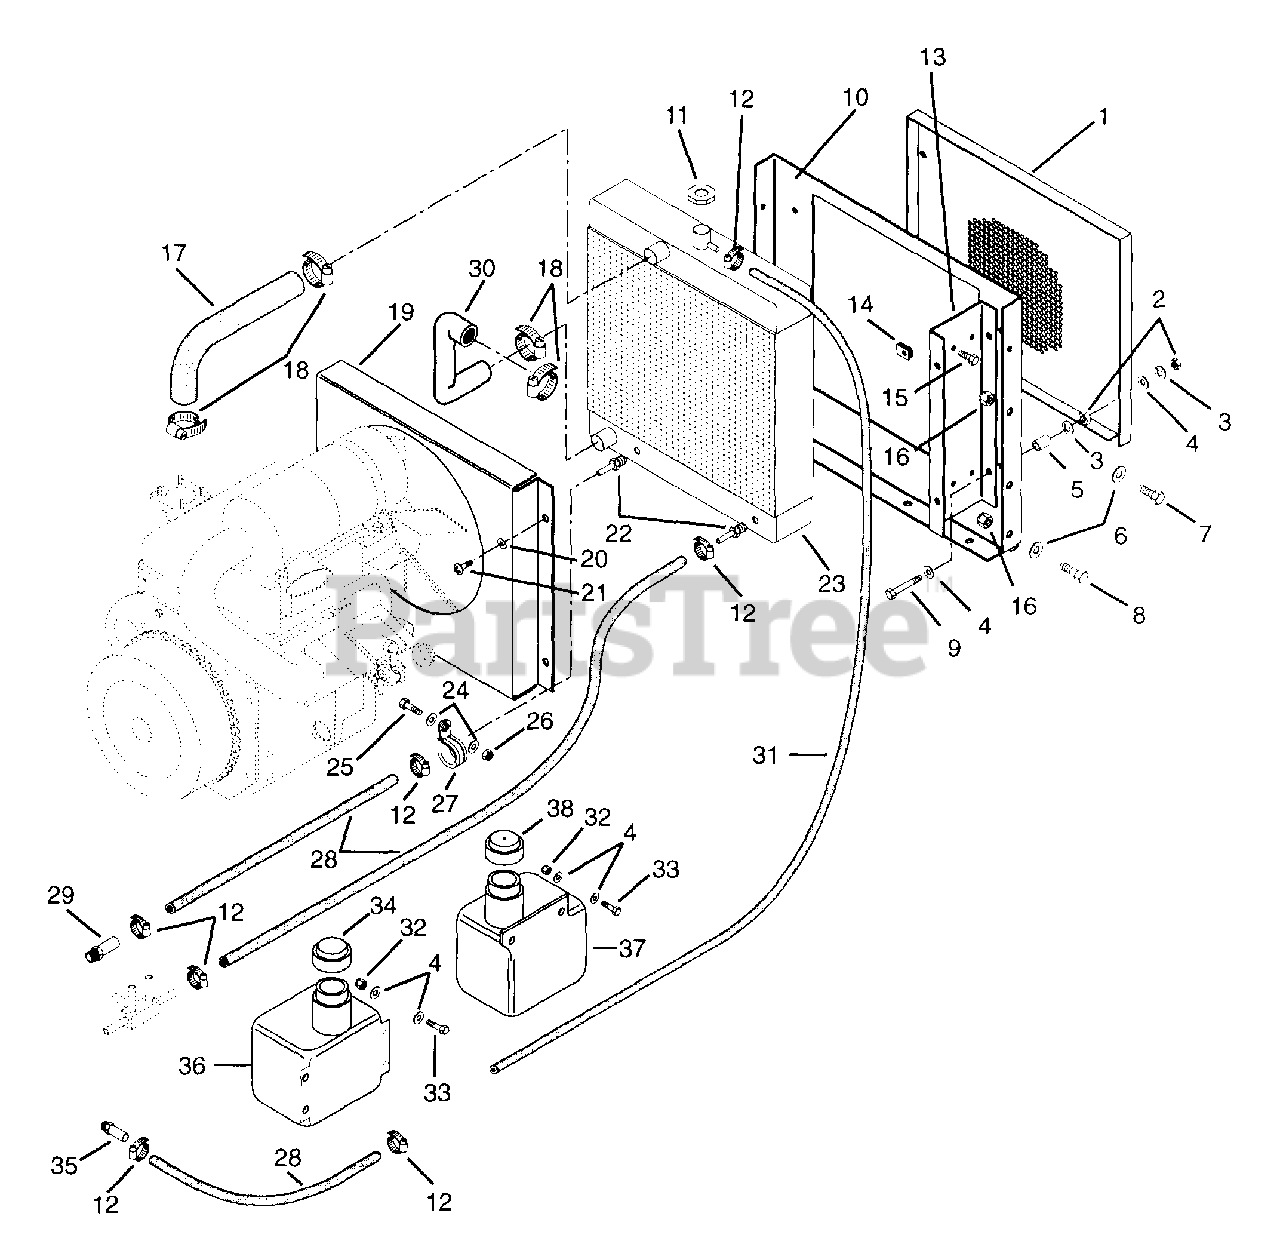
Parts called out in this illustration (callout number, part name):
1	Cover, Air
2	Nut-Hex .312-18 Grade 2
3	Washer-Lock .313 x .078
4	Washer-Flat-Steel .344 x .688 x .065
5	Bushing-Sleeve .407 x .625 x .750
6	Washer-Flat-Steel .531 x 1.062 x .095
7	Bolt-Hex .50-13 x 1 Grade 5
8	Bolt-Hex .50-13 x 1.50 Grade 5
9	Bolt-Hex .31-18 x 2.00 Grade 5
10	Mount, Radiator
11	Cap, Radiator
12	Hose Clamp
13	Bracket, Radiator
14	Nut-Retainer .25-20 x .56
15	Bolt-Hex .31-18 x .50
16	Nut-Locking-Nylon .50-13 Grade 5
17	Hose, Radiator Upper
18	Clamp-Hose 1.50 x .81 x 1.42
19	Weldment, Fan Cover
20	Washer-Flat-Steel .281 x .625 x .065
21	Screw-Machine .25-20
22	Adapter .38 Male Pipe to .38 Bead Tube
23	Radiator
24	Washer-Flat-Steel .406 x .812 x .065
25	Bolt-Hex .38-16 x 1.00 Grade 5
26	Nut-Locking-Nylon .375-16 Grade 2
27	Clamp, Cushioned Steel
28	Hose, Hydraulic
29	Fitting-Adapter .562-18
30	Hose, Lower Radiator
31	Hose, 5/16 Inside Diameter
32	Nut-Locking-Nylon .312-18 Grade 2
33	Bolt-Hex .31-18 x 1.00 Grade 5
34	Cap, 2" Vented
35	Connector, Hose
36	Tank, Plastic 2.0 Quart (Hydraulic)
37	Tank, Plastic 1.5 Quart (Coolant)
38	Cap, 1-5/8 Vented
